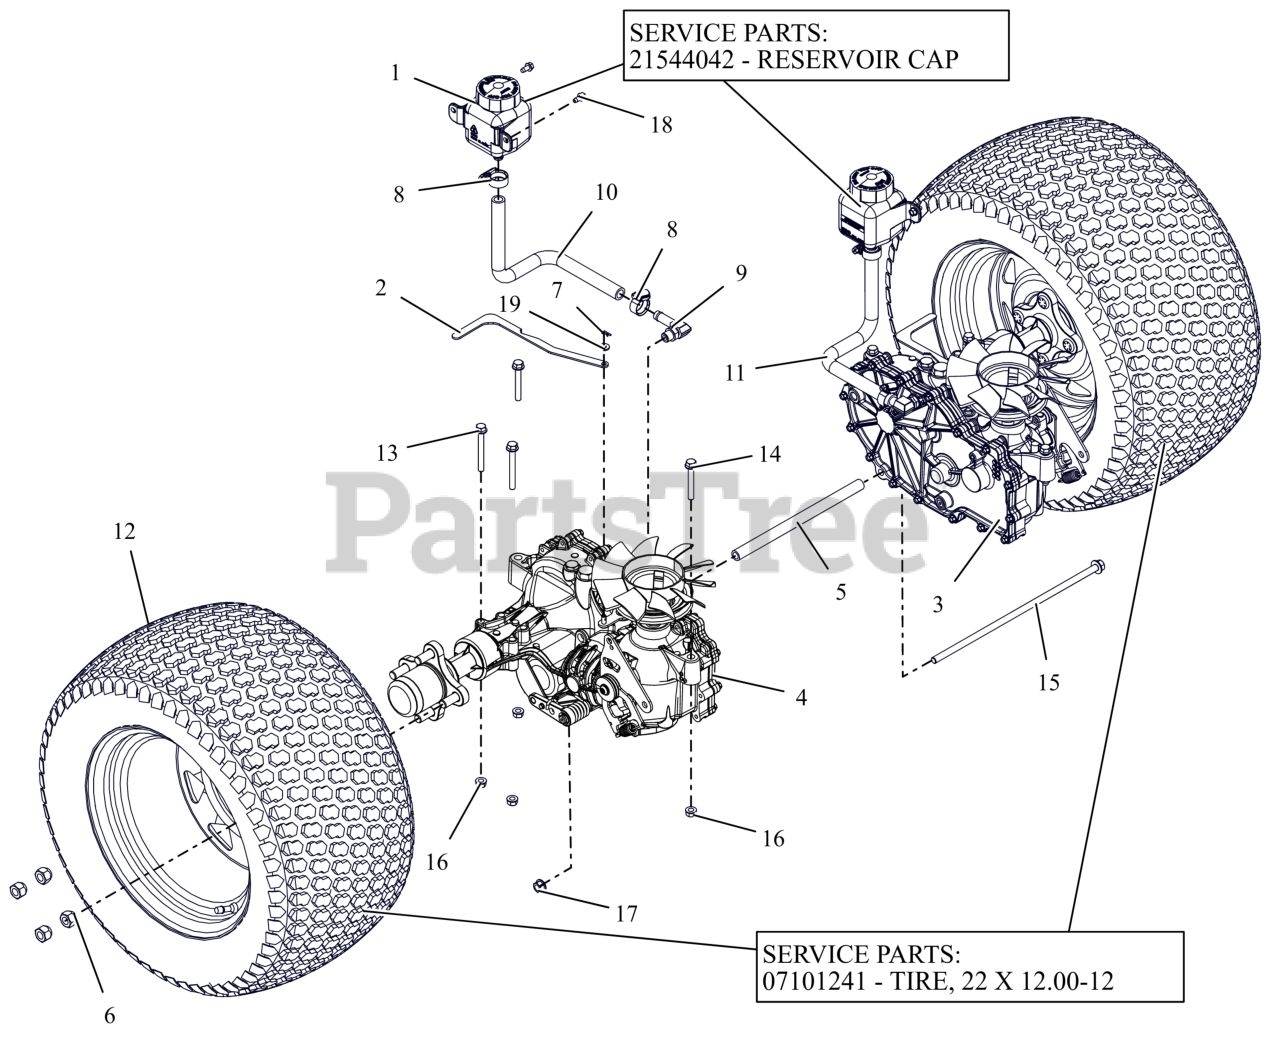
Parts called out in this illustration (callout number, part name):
1	TANK, EXPANSION
1	CAP, HYDRO RESERVOIR REPLAC.
2	BRKT, VALVE DUM
3	TRANSAXLE, ZT3200 LH
4	TRANSAXLE, RH ZT3200
5	SPCR, TRANSAXLE .406 ID X .630 OD X 9.95LG (BLACK)
6	NUT, WHEEL .50-20 ZCC
7	PIN, HAIR #225 .072X1.09
8	CLAMP,.88 DIA. HOSE
9	FITTING, HYD (90 DEG)
10	HOSE, FORMED EXPANSION -HD RH
11	HOSE, FORMED EXPANSION -HD LH
12	ASM, WHL/TIRE 22X12.00-12 K500
12	TIRE, 22X12.00-12
13	BLT,HEX-FLG .31-18X2.75 G5 ZCC
14	BLT,HEX-FLG .31-18X2.25 G5 ZCC
15	BLT, HEX-FLG 0.375-16X13 GR5 ZC120
16	NUT,LK-CTR-FLG .31-18 GF ZCC
17	NUT-LK-CTR-FLG .375-16 GF ZCC
18	SCR-TAP .25-20X.50 HWH ZCC
19	WSHR,FLT .281X.625X.065 ZCC
